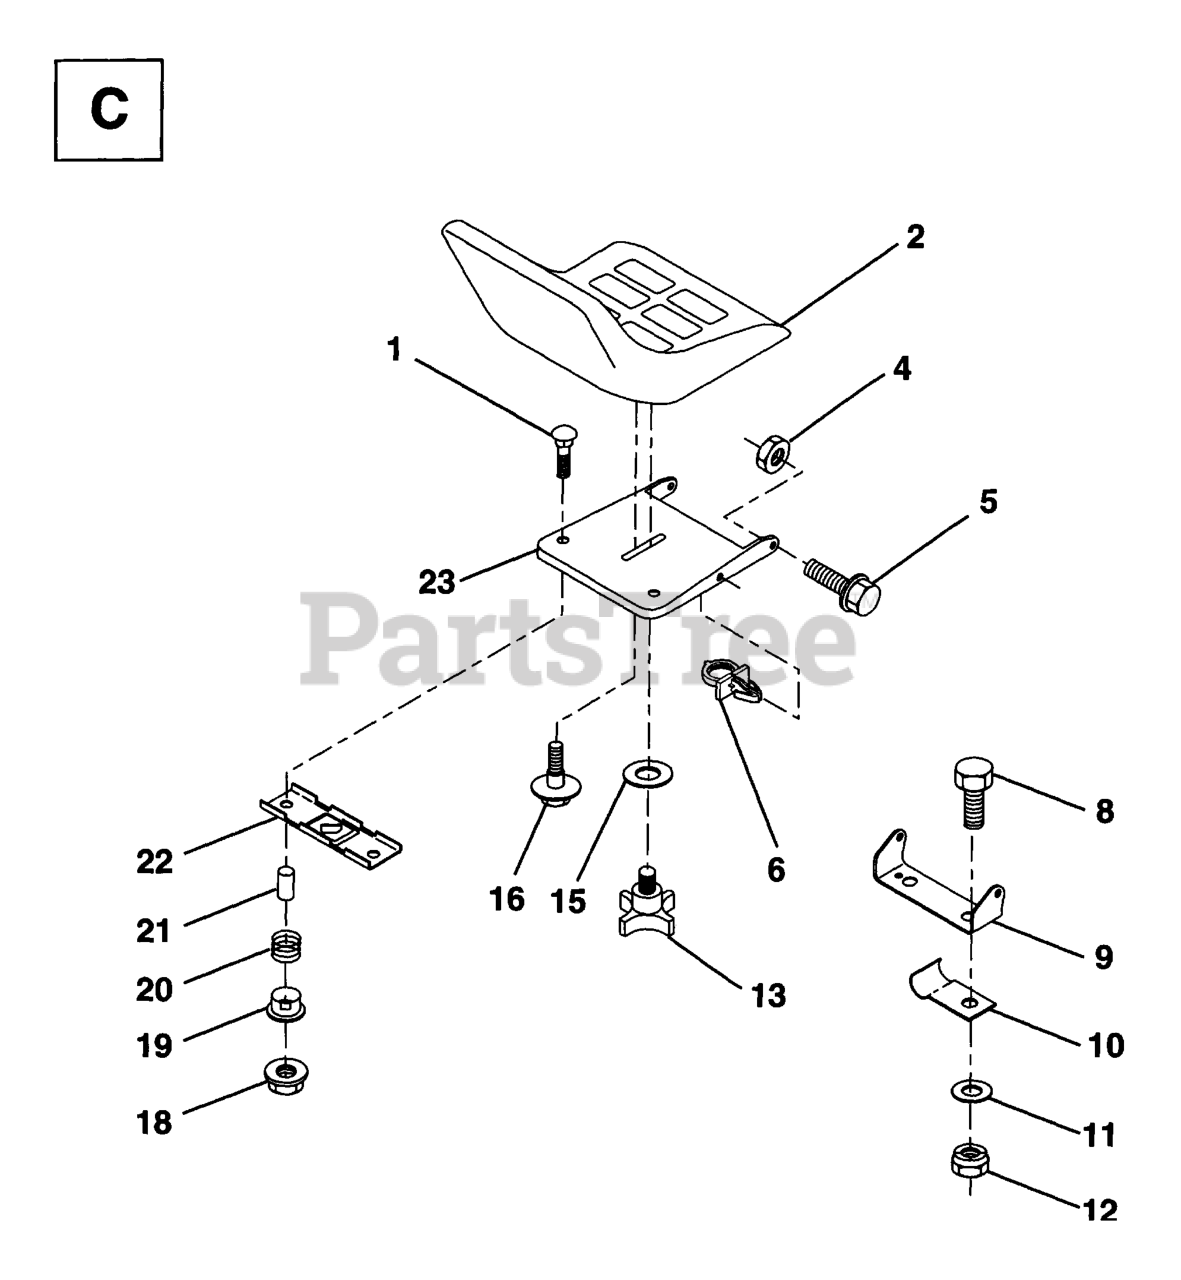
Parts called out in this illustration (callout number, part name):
1	Bolt Rdhd. Sht. Nk 1/4-20 x 1-3/8
2	SEAT
4	NUT.71038.31-18.HEX.NYLOCK
5	BOLT.SHOULDER.5/16-18
8	BOLT
9	SEAT PIVOT BRKT
10	CLIP,INSULATOR
11	WASHER 12/32X2X10GA
12	NUT
13	KNOB 1/2" YT
16	BOLT,SHOULD
18	NUT T
21	SPACER SPLIT 28X.96
22	BRKT SWITCH
23	SEAT PAN
